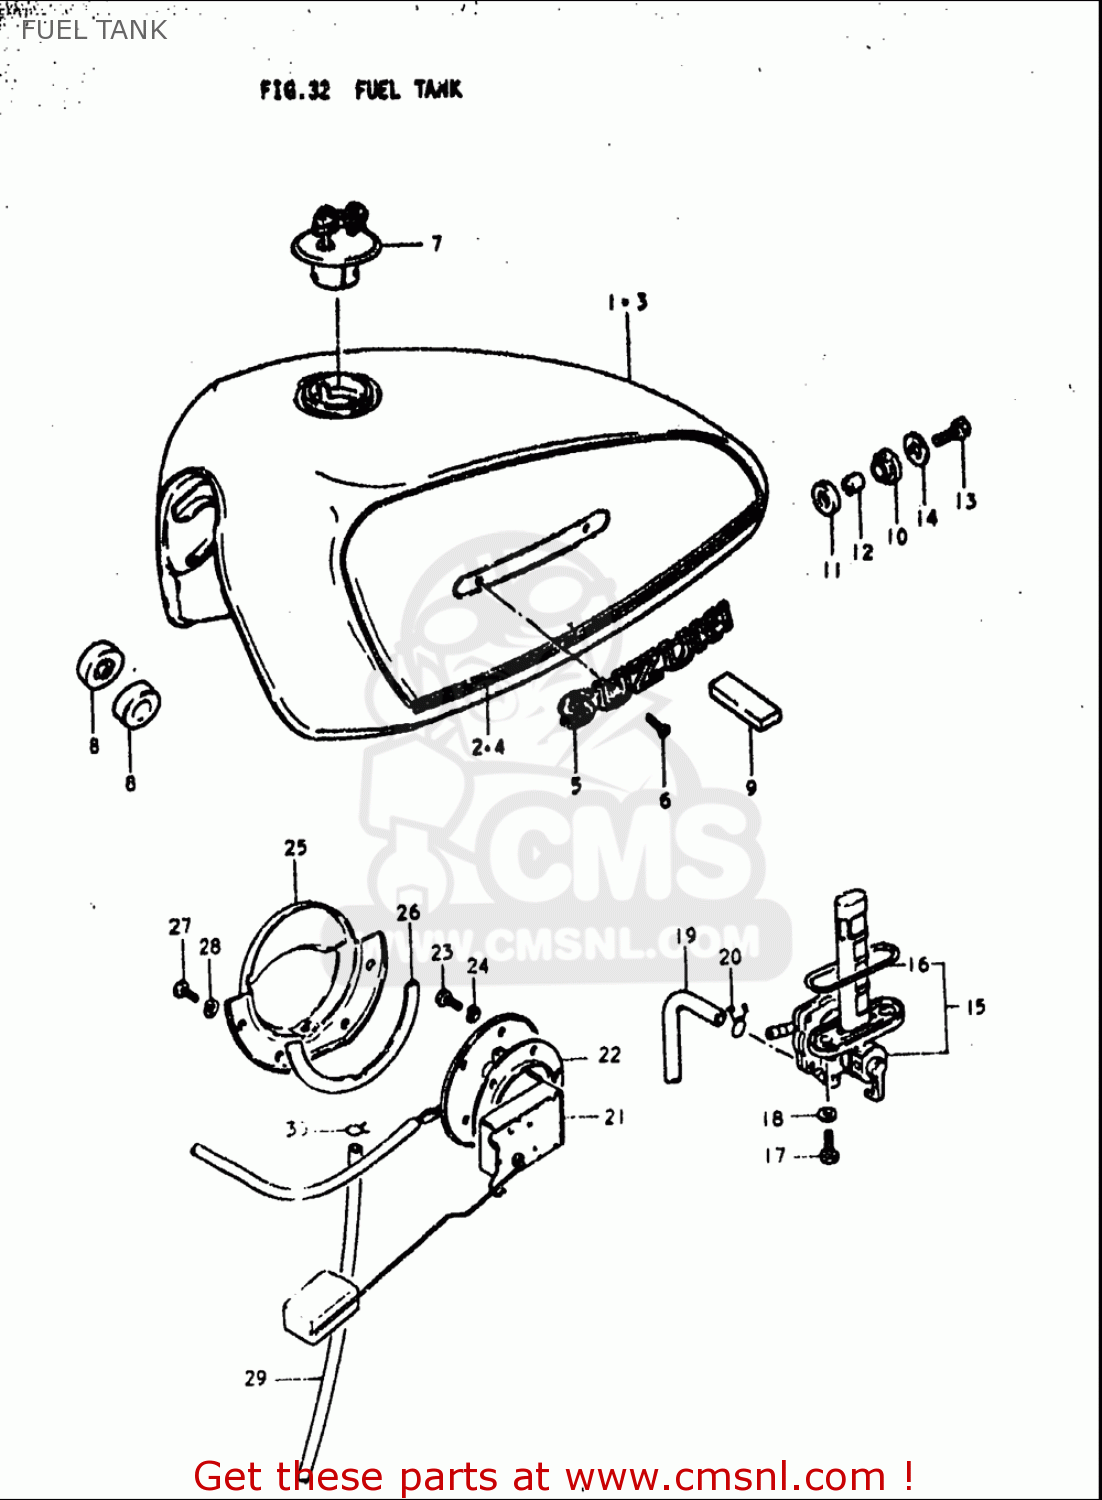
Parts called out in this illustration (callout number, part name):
5	EMBLEM,FUEL TANK
6	SCREW
7	CAP SET,FUEL TANK
8	CUSHION
9	CUSHION
10	CUSHION
11	CUSHION
12	SPACER(8.5X12X19)
13	BOLT
14	WASHER(8.5X28X1.6)
15	COCK ASSY,FUEL
16	O RING
17	BOLT(6X20)
18	GASKET(5.8X13X1.2) (NAS)
19	HOSE(7X10.2X2000)
20	CLIP
22	GASKET,FUEL LEVEL GAUGE (NAS)
23	BOLT
24	WASHER,LOCK
26	GASKET,FUEL DRAIN PLATE (NAS)
27	SCREW(5X6)
28	WASHER,LOCK
29	HOSE(5X8.2X2000)
30	CLIP
